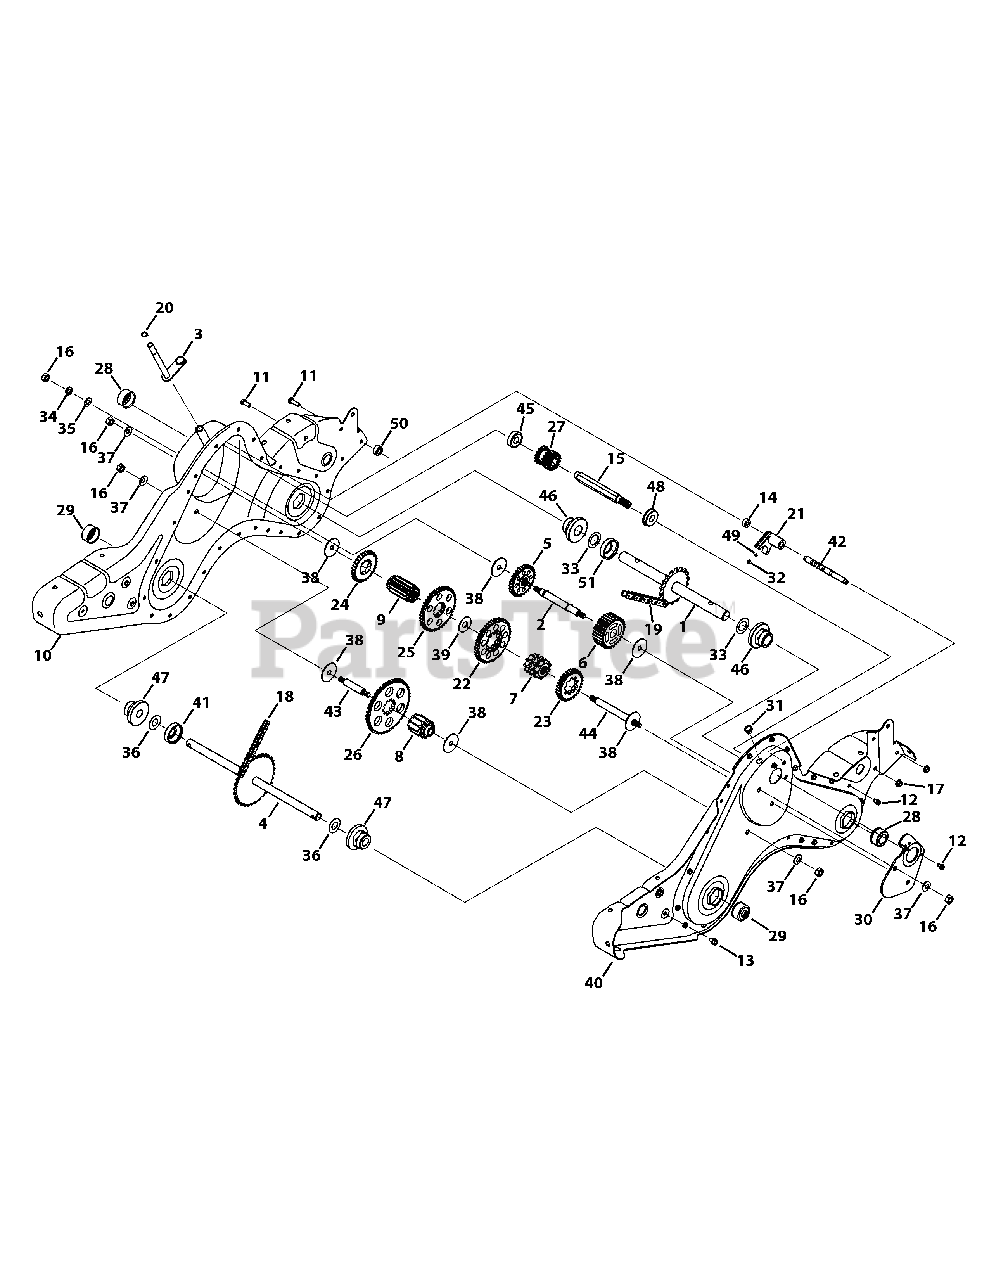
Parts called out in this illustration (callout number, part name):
1	Tine Shaft Assembly
2	Jack Shaft Assembly
3	Shift Input Shaft Assembly
4	Wheel Shaft Assembly, 33T
5	Reverse Idler Gear Assembly, 30T
6	Tine Idler Gear Assembly, 30T
7	Tine Input Sprocket Assembly, 9T
8	Wheel Input Sprocket Assembly, 10T
9	Gear Assembly, 11T
10	RH Chain Case Housing Assembly
11	Hex Head Screw, 5/16-18 x 1.00
12	Hex Washer Screw, 1/4-20 x .625
13	Hex Washer Screw, 5/16-18 x .750
14	Spacer, .505 x .88 x .440
15	Input Shaft, .75
16	Hex Nut, 7/16-20
17	Flange Lock Nut, 5/16-18
18	Endless Chain, #420 x 50
19	Endless Chain, #50 x 54
20	Snap Ring, .500
21	Clutch Collar
22	Gear Spur, 44T
23	Gear Spur, 30T
24	Gear Spur, 30T
25	Gear Spur, 44T
26	Gear Spur, 44T
27	Gear Spur, 16T
28	Shaft Seal, 1.0
29	Shaft Seal, .75
30	Positioner Gear Bracket
31	Tapered Cap Plug
32	Compression Spring, .230
33	Flat Washer, 1.03 x 1.62 x .03
34	Lock Washer, 7/16
35	Flat Washer,.474 x .879 x .064
36	Flat Washer, .760 x 1.50
37	Bell Washer, .45 x 1.00 x .062
38	Thrust Washer, .445 x 1.92 x .060
39	Flat Washer, 1.595 x .635 x .062
40	LH Chain Case Housing
41	Spacer, .75 x 2.0 x .50
42	Shaft Detent, .5 DIA
43	Jack Shaft, .625 x 2.385
44	Jack Shaft, .6250 x 5.0050
45	Ball Bearing, 17 x 40 x 12
46	Flange Bearing, 1.0 x 2.5 x 1.38
47	Flange Bearing, .75 x 2.5 x 1.38
48	Ball Bearing, 17 x 40 x 12:6203
49	Detent Ball, .250
50	Spacer, .315 x .750 x .375
51	Spacer, 1.0 x 2.0 x .5
